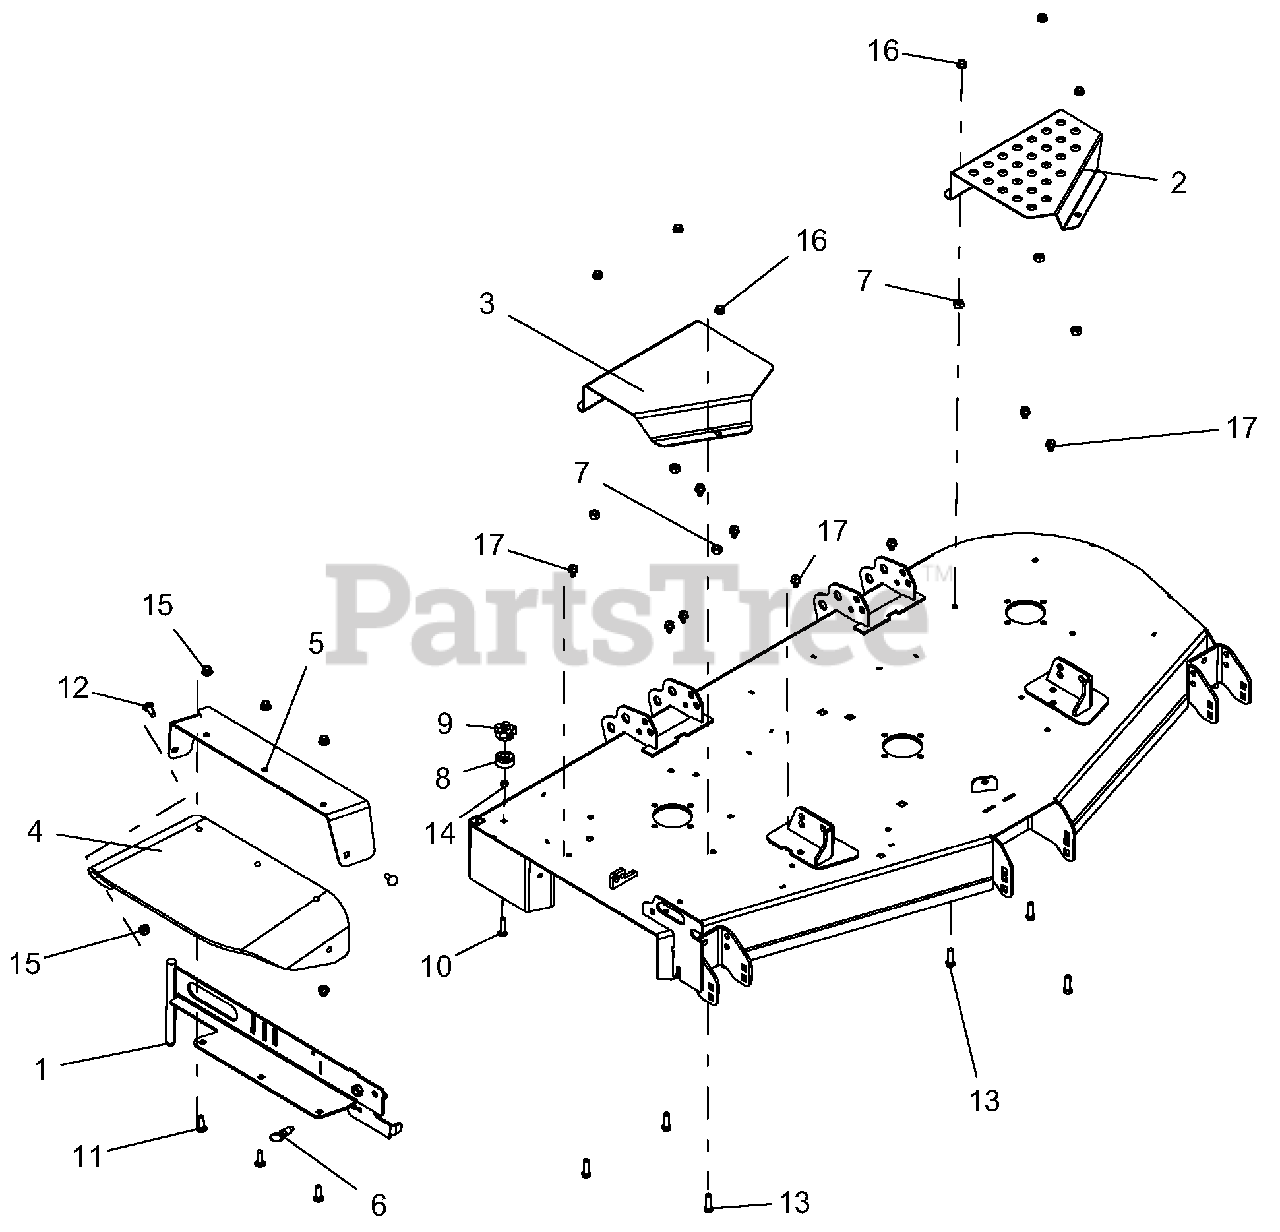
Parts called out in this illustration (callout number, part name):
1	WLDMT, 52"-60" DISCH CHUTE MTG-RED
2	GUARD, 60" LH DECK BELT-BLACK
3	GUARD, 60"-66" RH DECK BELT-BLACK
4	CHUTE, RUBBER DISCHARGE
5	KIT, PT DISCH CHUTE SUPT W/SAFETY DECALS-RED
6	PULL PIN,.50-13THDX.310 PLNGR
7	NUT-HEAVY HEX .38-16 YWZC
8	BUMPER, RECESSED 1.50 X .63 W/.31 HOLE
9	KNOB, CLAMPING
10	BLT-RDHDSQNK .31-18X1.50 G5 YWZC
11	BLT-RDHDSQNK .38-16X1.25 G5 YWZC
12	BLT-RDHDSQNK .38-16X1.00 G5 YWZC
13	BLT-HEX .38-16X1.25 GR5 YWZC
14	NUT-LK-CTR .31-18 YWZC
15	NUT-LK-NYL-FLG .38-16 YWZC
16	@NUT-SPNLK-FLG .375-16 YWZC
17	SCR-TAP .38-16X.50 HWH TR YWZ
